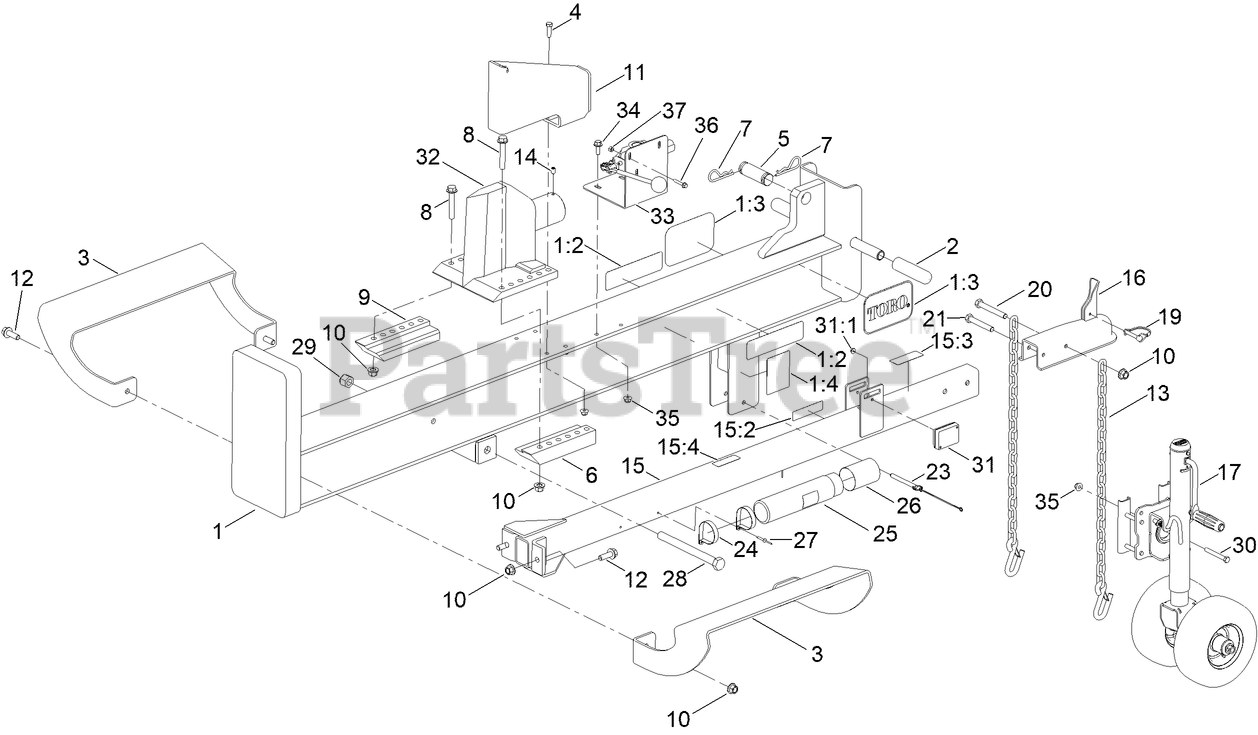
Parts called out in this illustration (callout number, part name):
1	BEAM ASM
1:3	DECAL
1:4	DECAL-WARNING, PIN
2	GRIP-HANDLE
3	PLATE-CATCH
4	SCREW-HH
5	PIN-PIVOT
6	BAR-SLIDE, LH
7	PIN-HAIR
8	SCREW-HF
9	BAR-SLIDE, RH
10	NUT-LOCK
11	DISLODGER BRACKET ASM
12	SCREW-HHF
13	CHAIN-SAFETY, TRAILER
14	SCREW-SET
15	TUBE ASM
15:2	DECAL-ARRESTOR, SPARK
15:3	DECAL-CAUTION
15:4	DECAL-WARNING, PINCH POINT
16	RECEIVER-HITCH, BALL
17	JACK ASM
19	PIN-LOCK
20	SCREW-HH
21	SCREW-HH
24	CLAMP-R
25	TUBE-MANUAL
26	CAP-HOUSING
27	RIVET-BLIND
28	BOLT-HH
29	NUT-LOCK, NI
30	SCREW-HH
31	LAMP-MARKER, FRONT SIDE
31:1	NUT-KEPS
32	WEDGE ASM
33	BRACKET-VALVE
34	SCREW-HHF
35	NUT-HF, NI
36	SCREW-HHF
37	NUT-LOCK, NI
